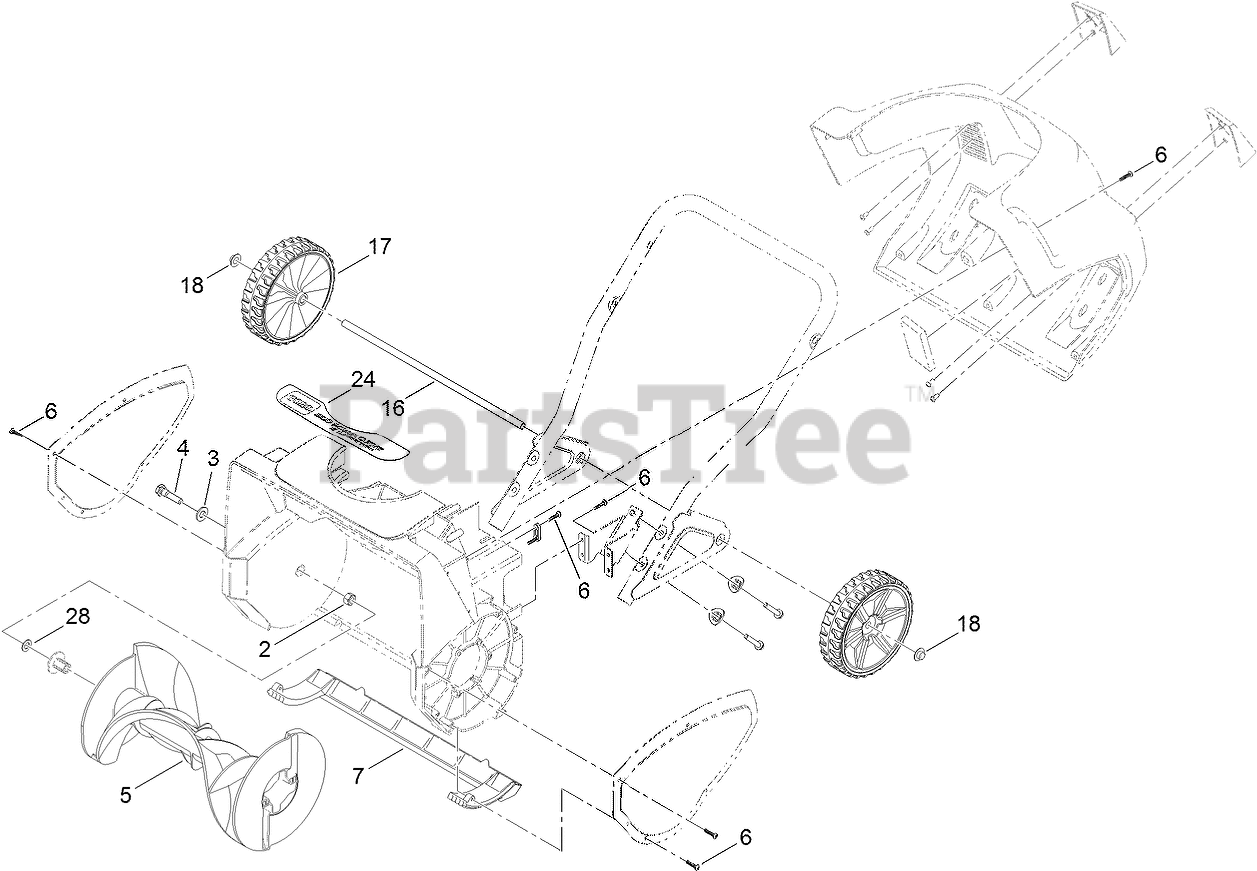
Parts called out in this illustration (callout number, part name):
2	NUT-LOCK
3	WASHER-FLAT
4	PIN-ROTOR
5	ROTOR ASM
6	SCREW-PPH
7	SCRAPER
16	AXLE-WHEEL
17	WHEEL ASM
18	RETAINER-PUSH ON
28	WASHER
